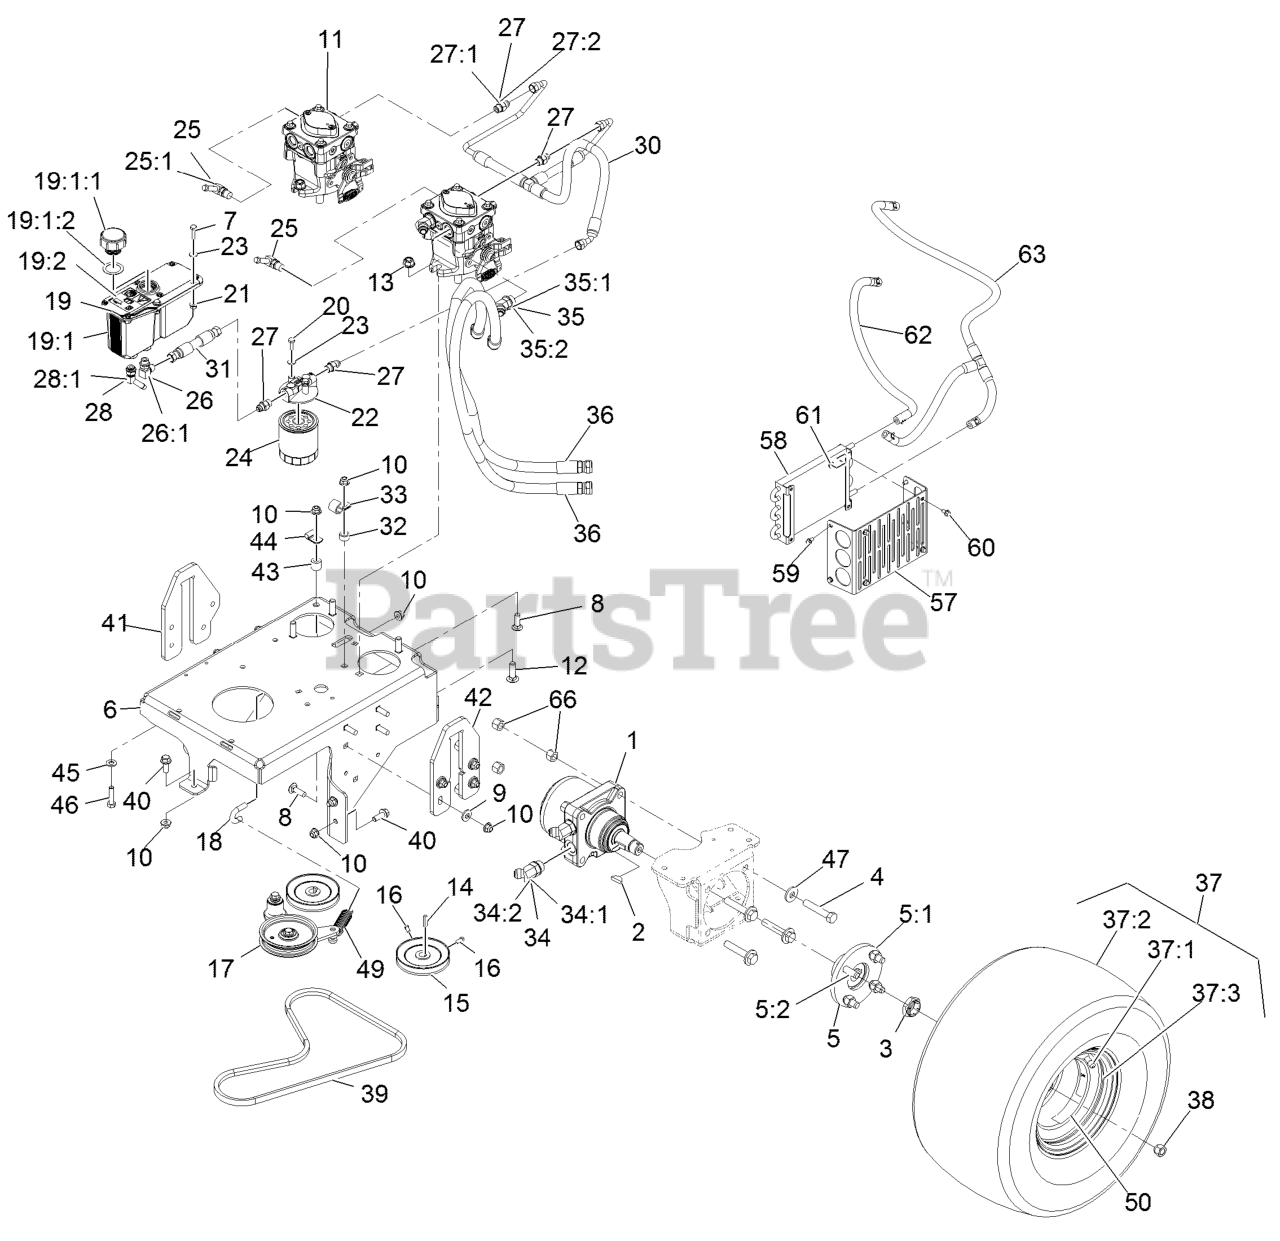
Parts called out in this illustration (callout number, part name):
1	Motor-Wheel
2	Key-Woodruff
3	Locknut
4	Screw-HH 1/2-13 X 2 3/4
5	Wheel Hub / Stud ASM
5:1	Hub-Wheel
5:2	Stud-Type, Drive
6	Base, Engine [red]
7	Screw-HH 1/4-20 X 1
8	Bolt-Carriage 3/8-16 X 1 1/4
9	Washer-Spring Disc 3/8
10	Nut-Nyloc 3/8-16 Flg
11	Pump - Hydraulic
12	Bolt-Carriage 7/16-14 X 1 1/2
13	Nut-HF, NI
14	Key-5Mm X 5Mm X 25Mm
15	Pulley-Pump
16	Setscrew-SQH 1/4-20 X 5/8
17	Pump Idler ASM
18	Anchor, Spring
19	ASM,Reservoir W/Decals
19:1:1	Cap-Reservoir, HYD
19:1:2	Gasket-Cap
19:2	Decal-Warning
20	Screw-HH 1/4-20 X 3/4
21	Nut-Hex 1/4-20 Side Lock
22	Filter-Head
23	Washer-1/4 Sae
24	Element, Oil Filter
25	Fitting-Barbed, 90 DEG
25:1	O-Ring
26	Fitting-HYD, 90 DEG
26:1	O-Ring-Sae #6
27	Adapter-Straight
27:1	O-Ring-Sae #6
27:2	O-Ring-37 Flare #6
28	Fitting-Barbed, 45 DEG
28:1	O-Ring
30	Hose Assembly - Charge
31	HYD Hose ASM
32	Spacer-Wheel
33	Clip-Loom 5/8
34	Fitting-HYD, 45 DEG
34:1	O-Ring-Sae #10
34:2	O-Ring-37 Flare #8
35	Fitting-HYD, 45 DEG
35:1	O-Ring-Sae #8
35:2	O-Ring-37 Flare #8
36	HYD Hose ASM
37	Wheel/Tire ASM
37:1	Rim-8 Inch
37:3	Stem-Valve
38	Nut-Lug 1/2-20
39	Belt-V
40	Screw HHF 3/8-16 X 1
41	Plate-Lift, RH
42	Plate, Lift LH
44	Clip-Tube
45	Washer-3/8 Sae
46	Screw-HH 3/8-16 X 1 1/2
47	Washer-Spring Disc 1/2
49	Spring-Extension
50	Decal-Torque, Wheel Hub Lug
57	Bracket, Cooler Mounting
58	Cooler-Oil
59	Screw-HWH 1/4-20 X 1/2 Taptite
60	Screw-HHF
61	Nut-Keps
62	Hose-Hydraulic
63	Hose ASM-HYD LP 3/8
66	Nut-Nyloc 1/2-13
